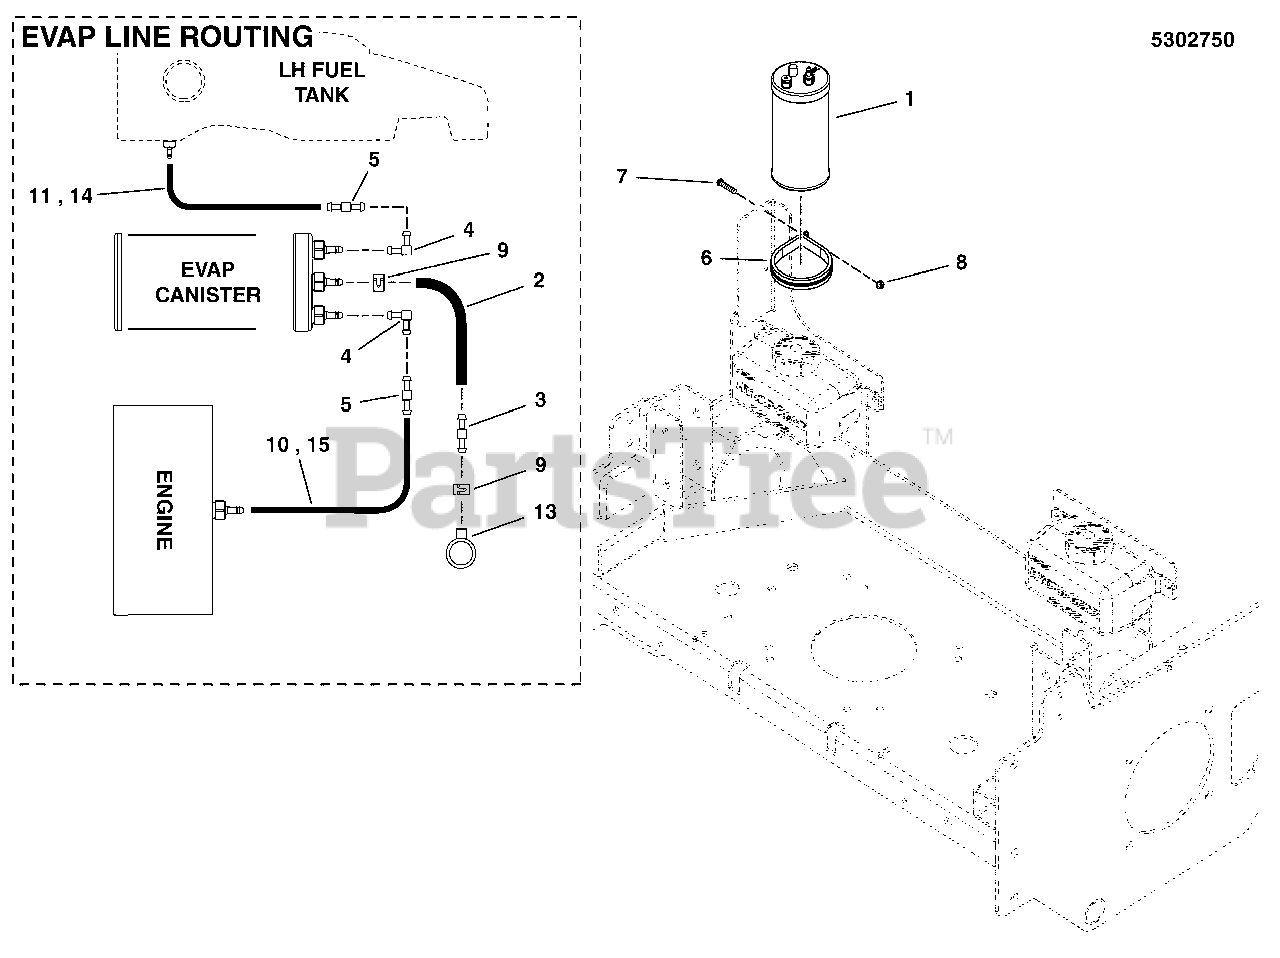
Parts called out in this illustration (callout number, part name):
1	CNSTR, CARB, 6 GAL
2	HOSE, FORMED, EVAP CANISTER
3	FITTING, STRAIGHT, 10MMX10MM, PLASTIC
4	FITTING, 90 DEG, 3/16X3/16, SANTOPRENE
5	FITTING, STRAIGHT, 3/16X3/16, PLASTIC
6	CLAMP, 3" ID, CUSHIONED, STAINLESS
7	SCREW, 1/4-20 X 3/4 ALLEN BH
8	NUT, 1/4-20 HEX NYLOCK FLANGE (5025391)
9	CLAMP, HOSE
10	HOSE, VAPOR, 5MM ID, 16.00 LG
11	HOSE, VAPOR, 5MM ID, 7.00 LG
12	DECAL, EPA CERT - 49 STATE
13	DUST FILTER, CANISTER
14	HOSE, VAPOR, 5MM ID, 8.00" LG
15	HOSE, VAPOR, 5MM ID, 42.00" LG
